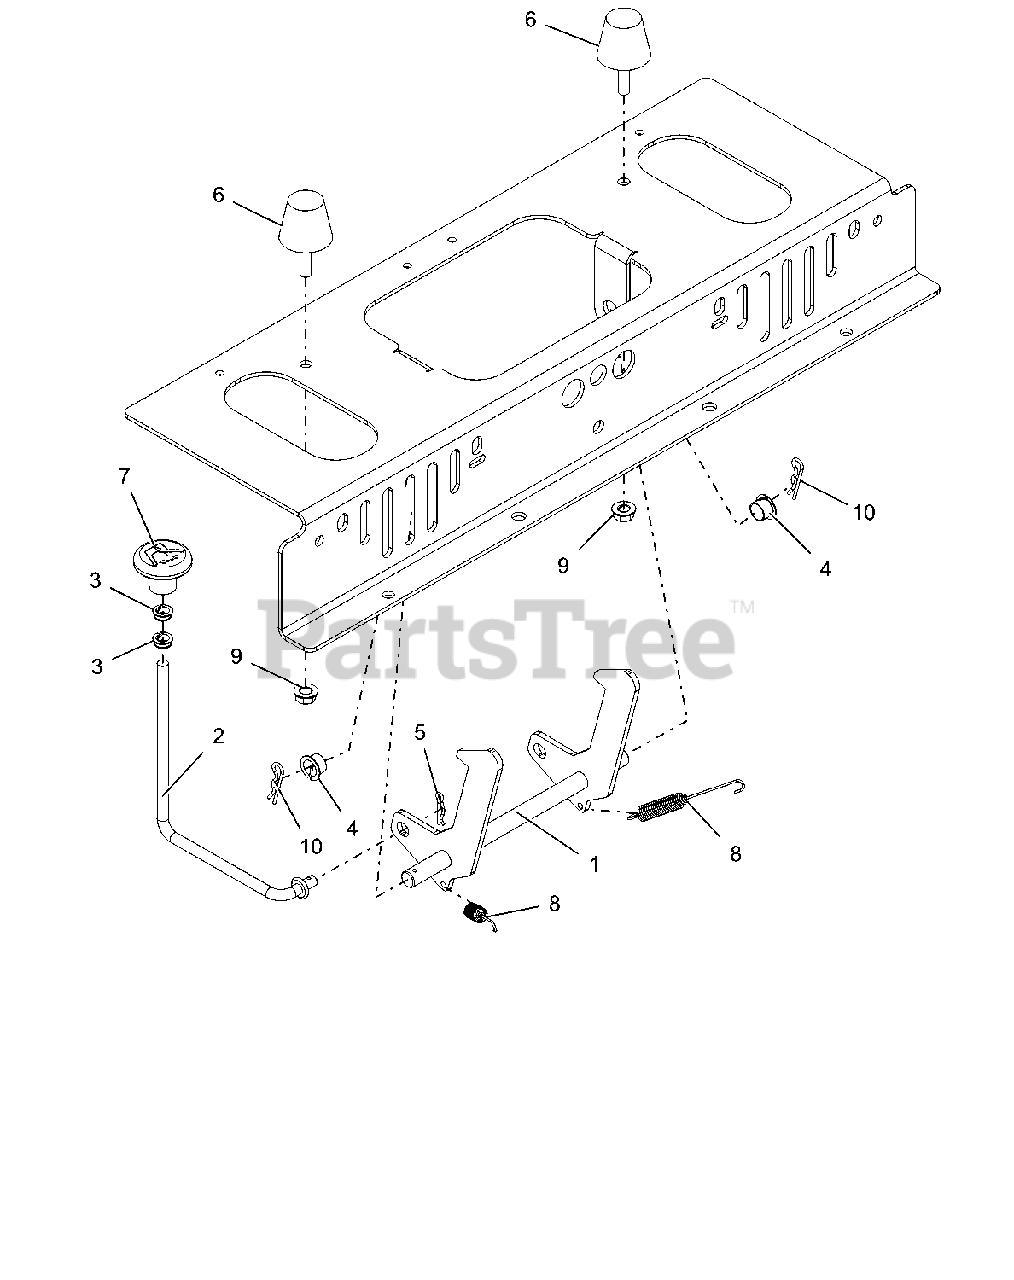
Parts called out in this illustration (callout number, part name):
1	SEAT LATCH WLDMT - LOW FILM
2	LINKAGE, SEAT RELEASE
3	BUSHING, POLYLINER-.38 SNAPIN
4	BUSHING, POLYLINER-.50 SPLIT
5	PIN-HAIR, ENDRIES #25 YWZC
6	BUMPER,STUD MOUNTED CONE SHAPE
7	KNOB, PUSH/PULL
8	SG-TENS .043X.44X3.31 WLD 5.8
9	NUT-SPNLK-FLG .312-18 YWZC
10	PIN-HAIR INT .08X.38X1.42 YWZC
